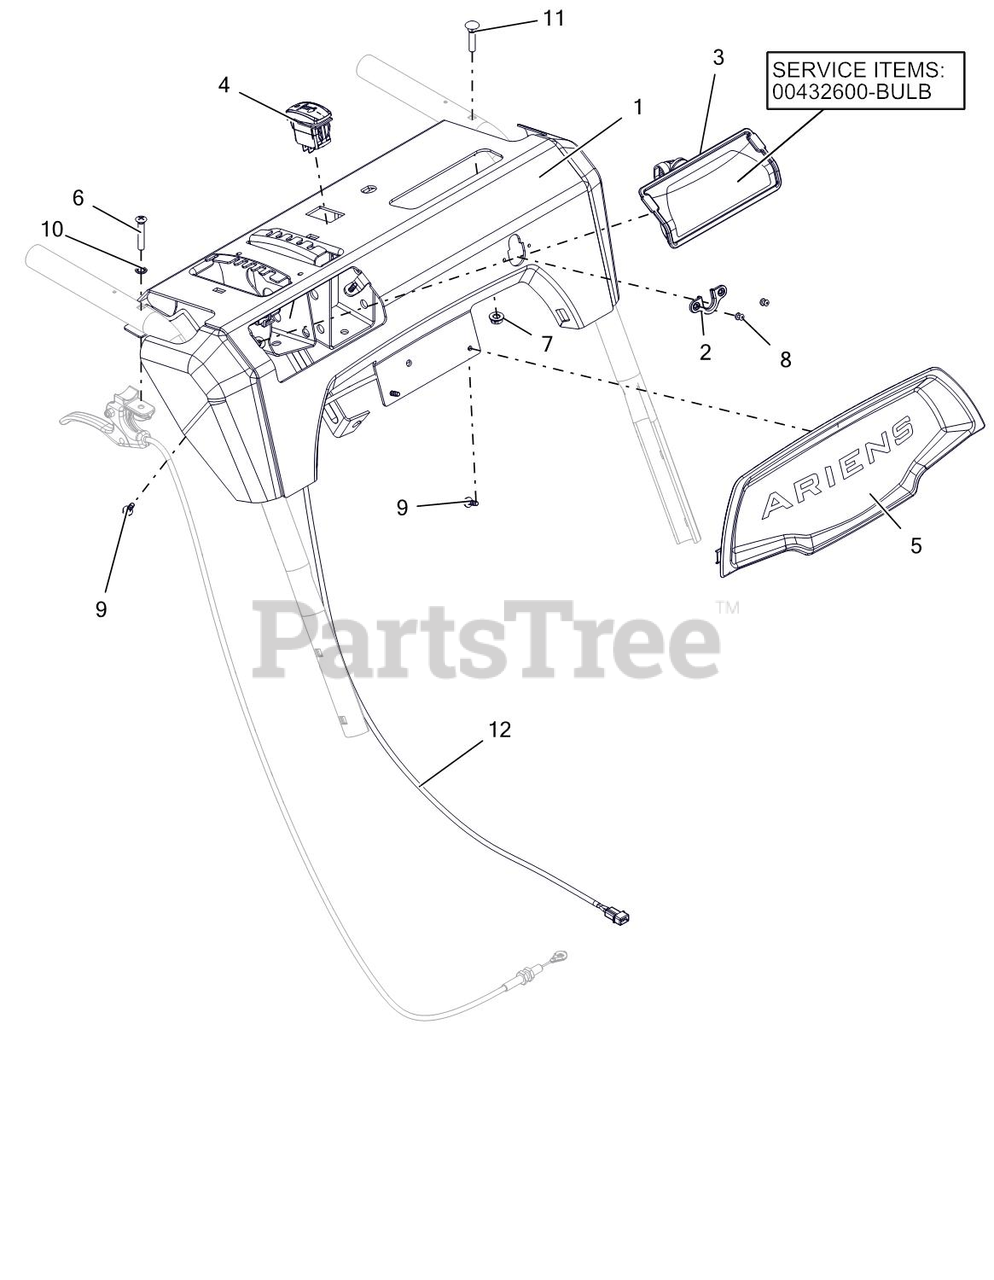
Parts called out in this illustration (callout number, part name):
1	CONTROL PANEL W/DECAL FRIC-TRK
2	GROMMET, CABLE, QUICK TURN 2
3	BULB, LIGHT-HALOGEN 20W
3	HEADLIGHT ASY, HALO 20W 2SHOT
4	SWITCH,ROCKER SPST-ON/OFF
5	BEZEL, DASH - ARIENS LG DASH
6	SCR-MCH .25-20X1.50 OVAL HD
7	@NUT-LK-CTR-FLG .25-20 YWZC
8	RVT-POP #43 .125X.313 STL ZINC
9	SCR-TAP #10X.50 BOSS INDHXHD
10	WSHR-LK-INT .250 TH TYA
11	BLT-RDHDXLSQNK.25-20X1.25 G5ZC
12	HARNESS, LIGHT & WARMER
